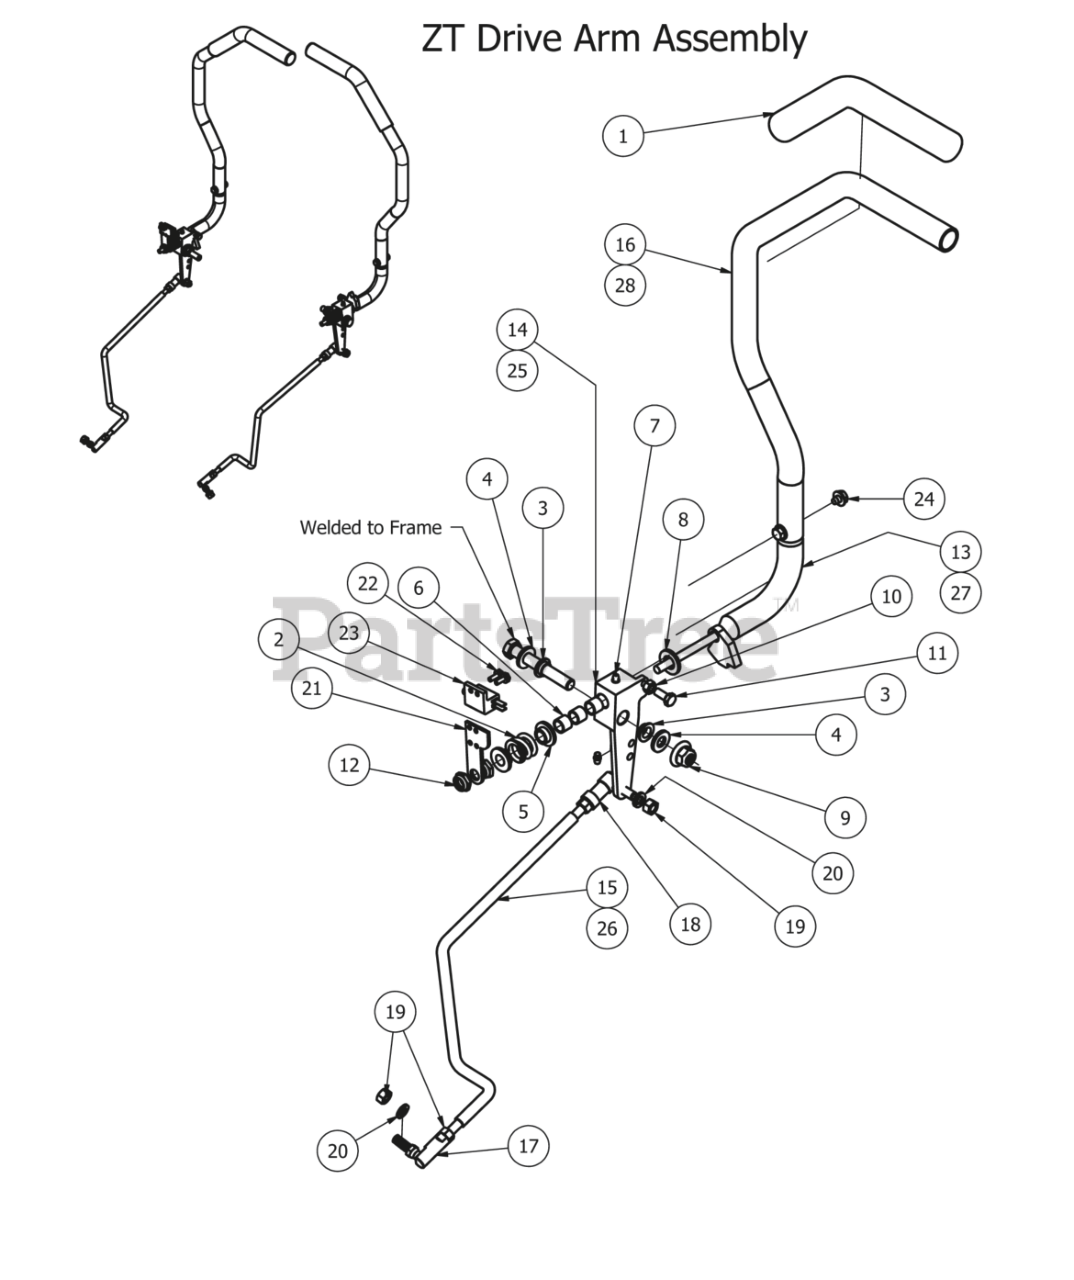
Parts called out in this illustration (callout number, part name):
1	Rubber Grip
2	Drive Lever Spring
3	Bushing for 2012 Drive Arms
4	.505x1x.125 Oil Impregnated washer
5	.515 ID Nylon Shoulder Washer
6	.507 ID Nylon Bushing
7	1/4" Drive in Grease Fitting
8	.635 ID Plastic Washer
9	1/2-13 Nylon Flange Nut-Orange
11	5/16" x 3/4" Hex Bolt
12	1/2" Nylcock Nut (1/2 Jam)
13	Steering Arm Elbow Left
14	Drive Arm Lever Housing (Left)
15	Transaxle Drive Rod (Right)
16	ZT Direction Steering Arm (Left)
17	3/8-24 Ball Joint
18	3/8-24 Quick Release Ball Joint
19	3/8" Fine Threaded Jam Nut
20	3/8" Lock Washer
21	Switch Bracket-ZT
22	12-24x 1/2 HWH Bolt
23	Safety Switch
24	5/16-18 1/2 HWH Bolt-Steering
25	ZT Drive Arm Lever Housing (Right)
26	Transaxle Drive Rod (Left)
27	Stering Arm Elbow (Right)
28	ZT Direction Steering arm (Right)
